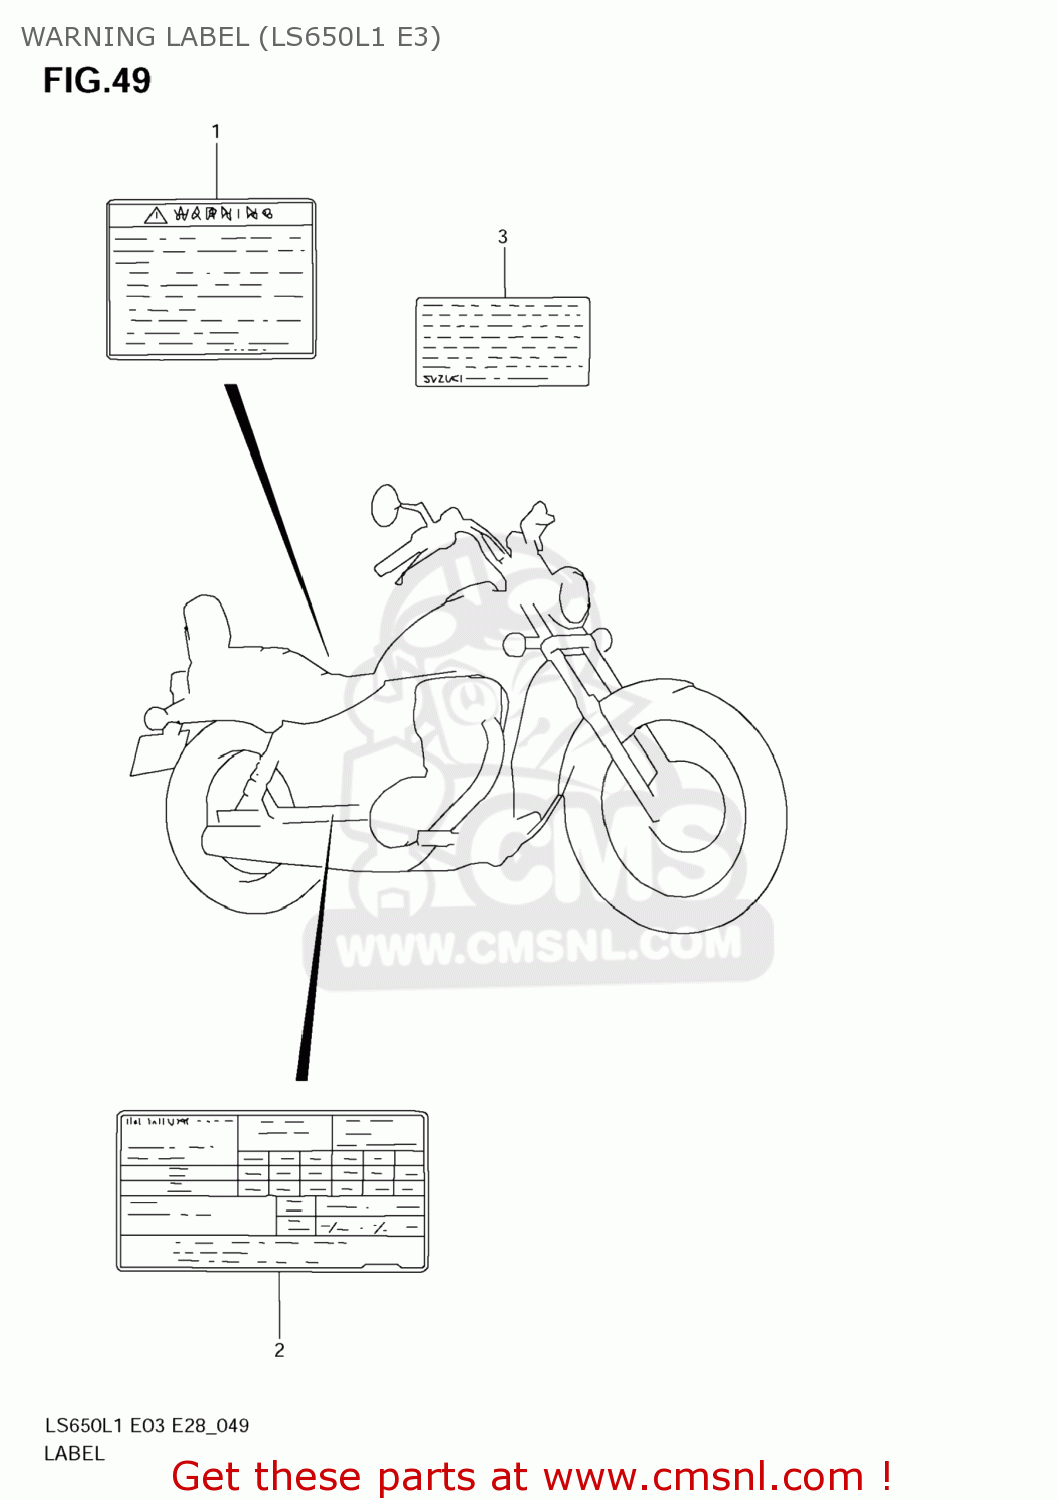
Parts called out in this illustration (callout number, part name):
1	LABEL,GENERAL WARNING
2	LABEL,TIRE INFORMATION
3	LABEL,MANUAL NOTICE
4	MANUAL,OWNER'S
